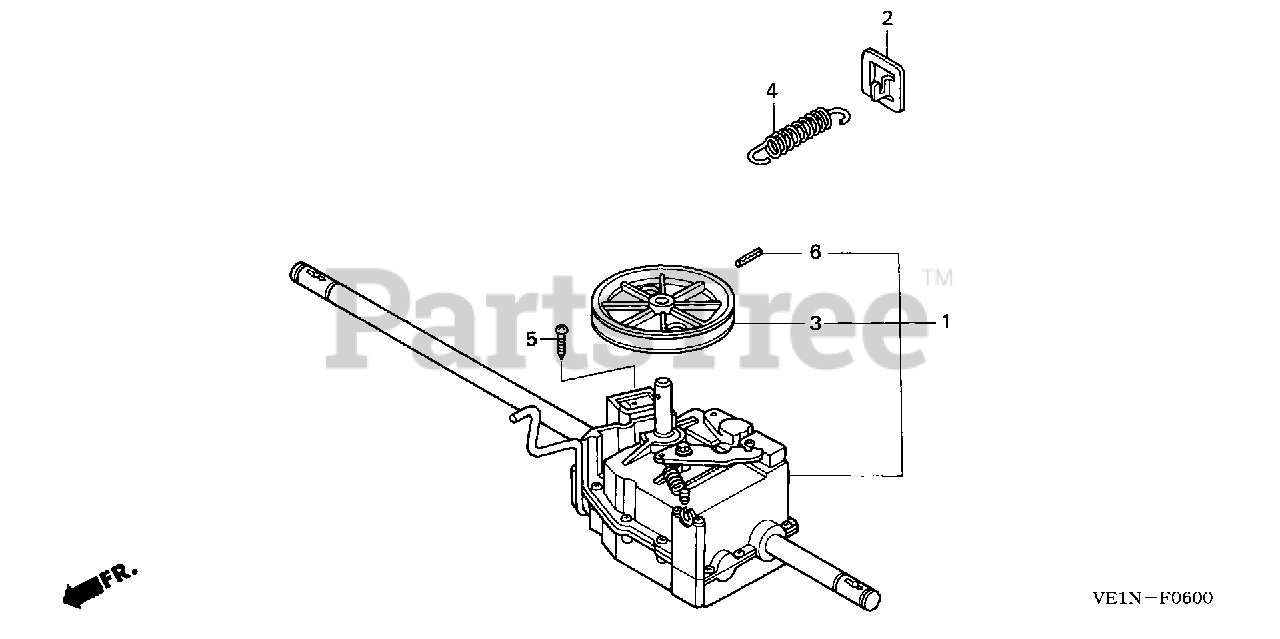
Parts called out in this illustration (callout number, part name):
1	TRANSMISSION ASSY.
2	PLATE, TENSION SPRING
3	PULLEY, DRIVEN
4	SPRING, WHEEL TENSION
5	SCREW, TAPPING (5X12) (PO)
6	PIN, SPRING (5X36)
